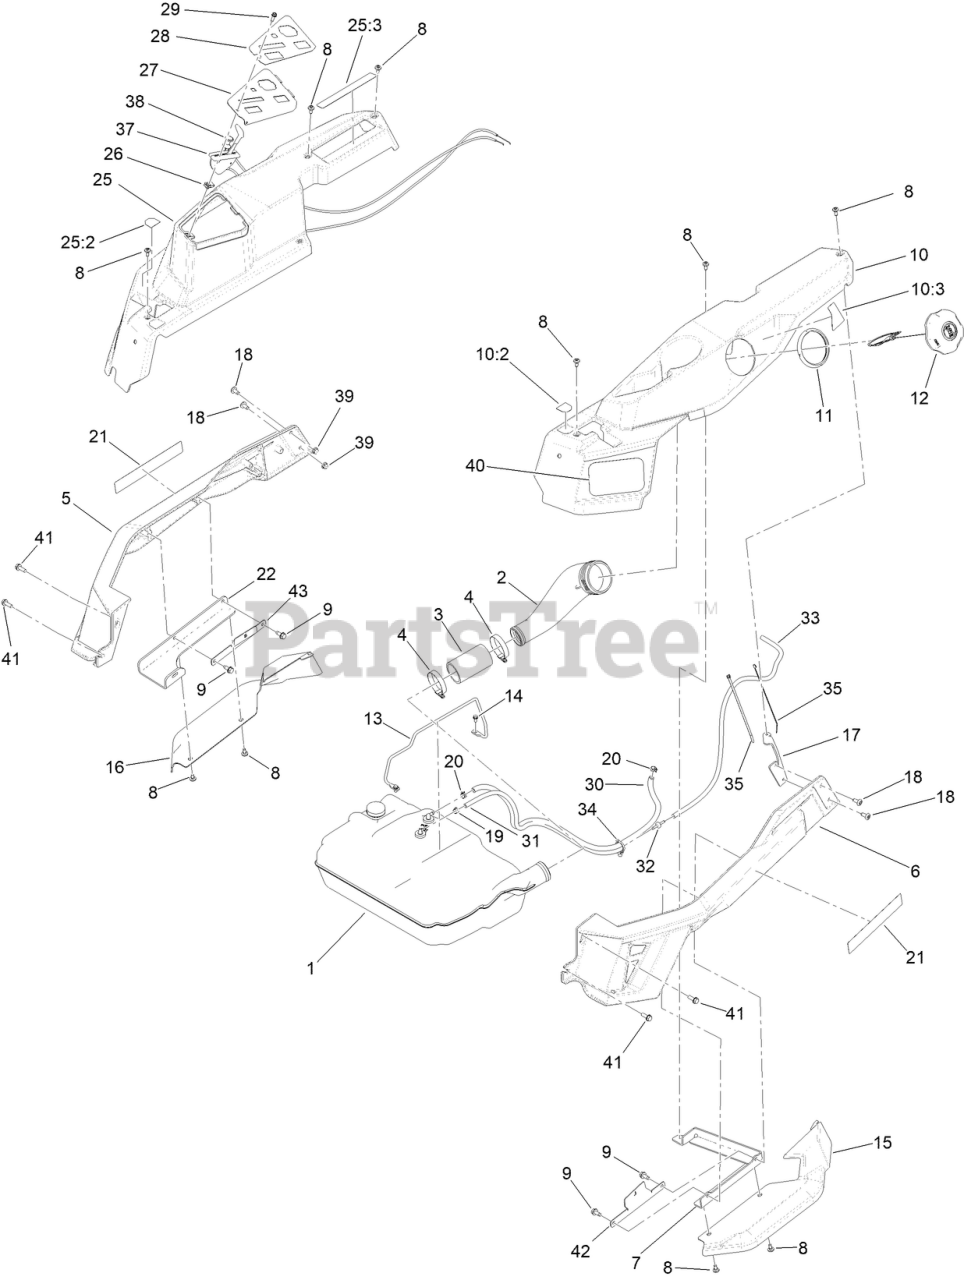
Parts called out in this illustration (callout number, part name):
1	TANK ASM - FUEL
2	NECK-FILLER, FUEL
3	HOSE-FILLER, FUEL
4	CLAMP-HOSE
5	CAST-TUBE, RH [RED]
6	CAST-TUBE, LH [RED]
7	MOUNT-POD BRACKET LH
8	SCREW-SHOULDER
9	SCREW-HWHTF
10	POD ASM - LH W/DECALS
10:2	DECAL-CONTROL LEVER, LH
10:3	DECAL-FUEL FILL
11	RING-RETAINING
12	CAP-FUEL, RATCHETING
13	ROD-HOLD DOWN
14	SCREW-HWH
15	FENDER-TIME CUTTER, LH
16	FENDER-TIME CUTTER, RH
17	BRACKET-REAR POD, LH
19	CLAMP-HOSE
20	CLAMP-HOSE
21	DECAL-TITAN
22	BRACKET-MR SPRING
25	POD ASM - RH , MR W/DECALS
25:2	DECAL-CONTROL LEVER, RH
25:3	DECAL - MYRIDE
27	PANEL-CONTROL
28	DECAL - CONTROL PANEL
29	SCREW-HWHTF
30	HOSE-FUEL
31	HOSE-FUEL
32	ADAPTER ORIFICE
33	HOSE-LP
34	CLIP-TIE
35	TIE-CABLE
37	CABLE-THROTTLE
38	CABLE-CHOKE
39	NUT-HF
40	DECAL - TORO LOGO
41	SCREW-TAPTITE
42	BRACKET-ALIGNMENT, POD LH
43	BRACKET- ALIGNMENT, POD RH MR
